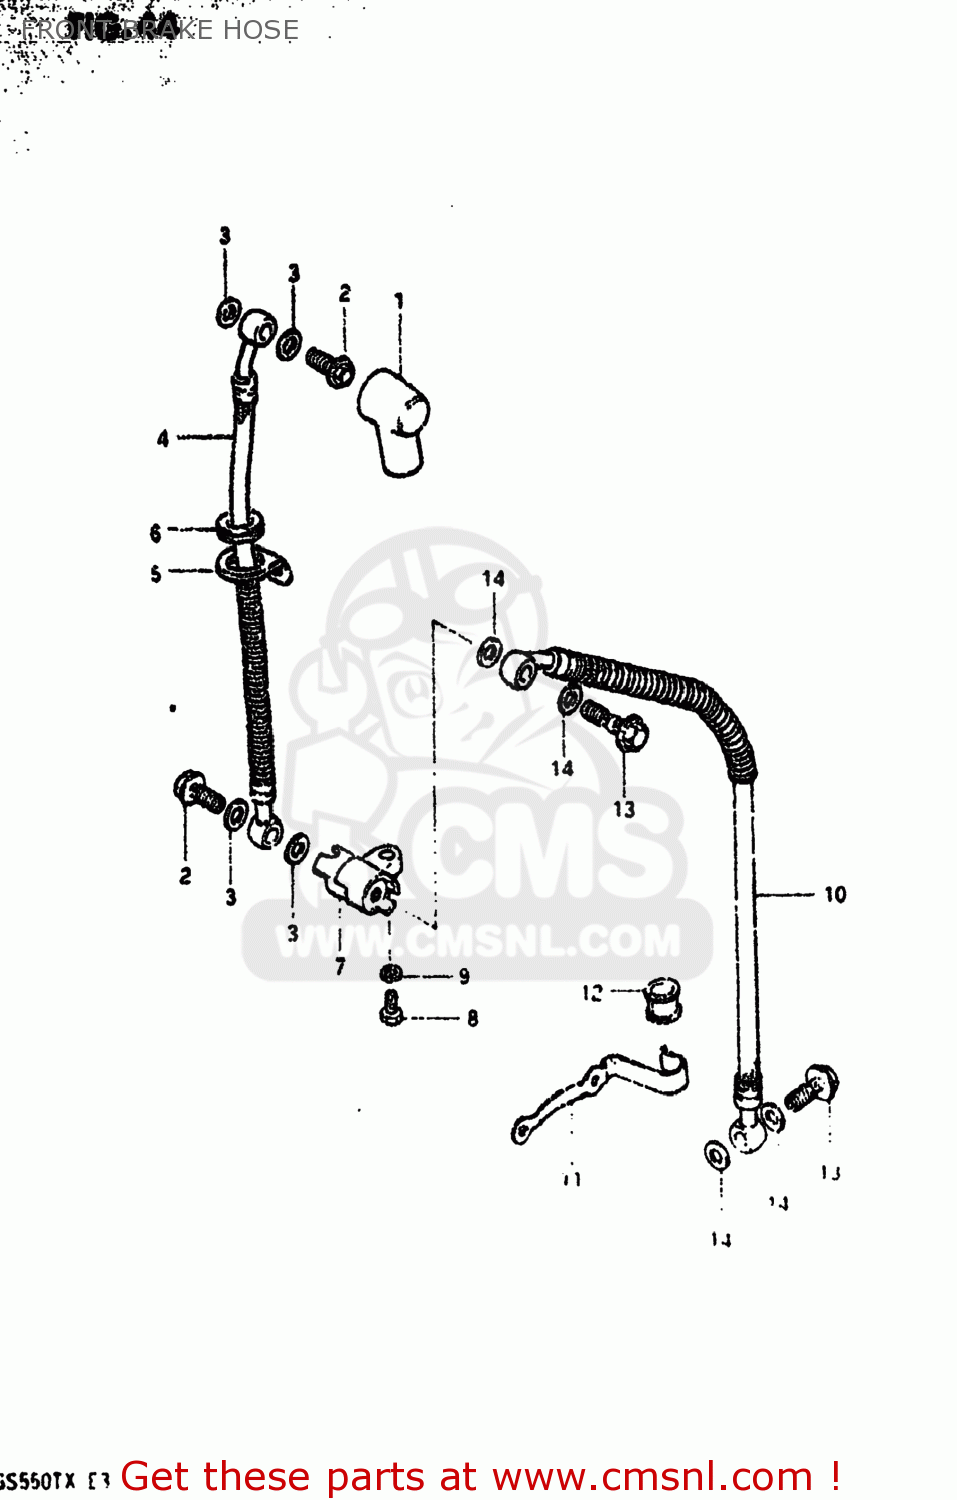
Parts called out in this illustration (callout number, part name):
1	BOOT,MASTER CYLINDER
2	BOLT,UNION
3	WASHER
4	HOSE,BRAKE NO.1
5	GUIDE,BRAKE HOSE
6	GROMMET
7	JOINT,BRAKE HOSE
8	BOLT
9	LOCK WASHER
10	HOSE,BRAKE NO.2
11	GUIDE,BRAKE HOSE NO.2
12	BUSH,BRAKE HOSE GUIDE,NO.2
13	BOLT,UNION
14	WASHER
